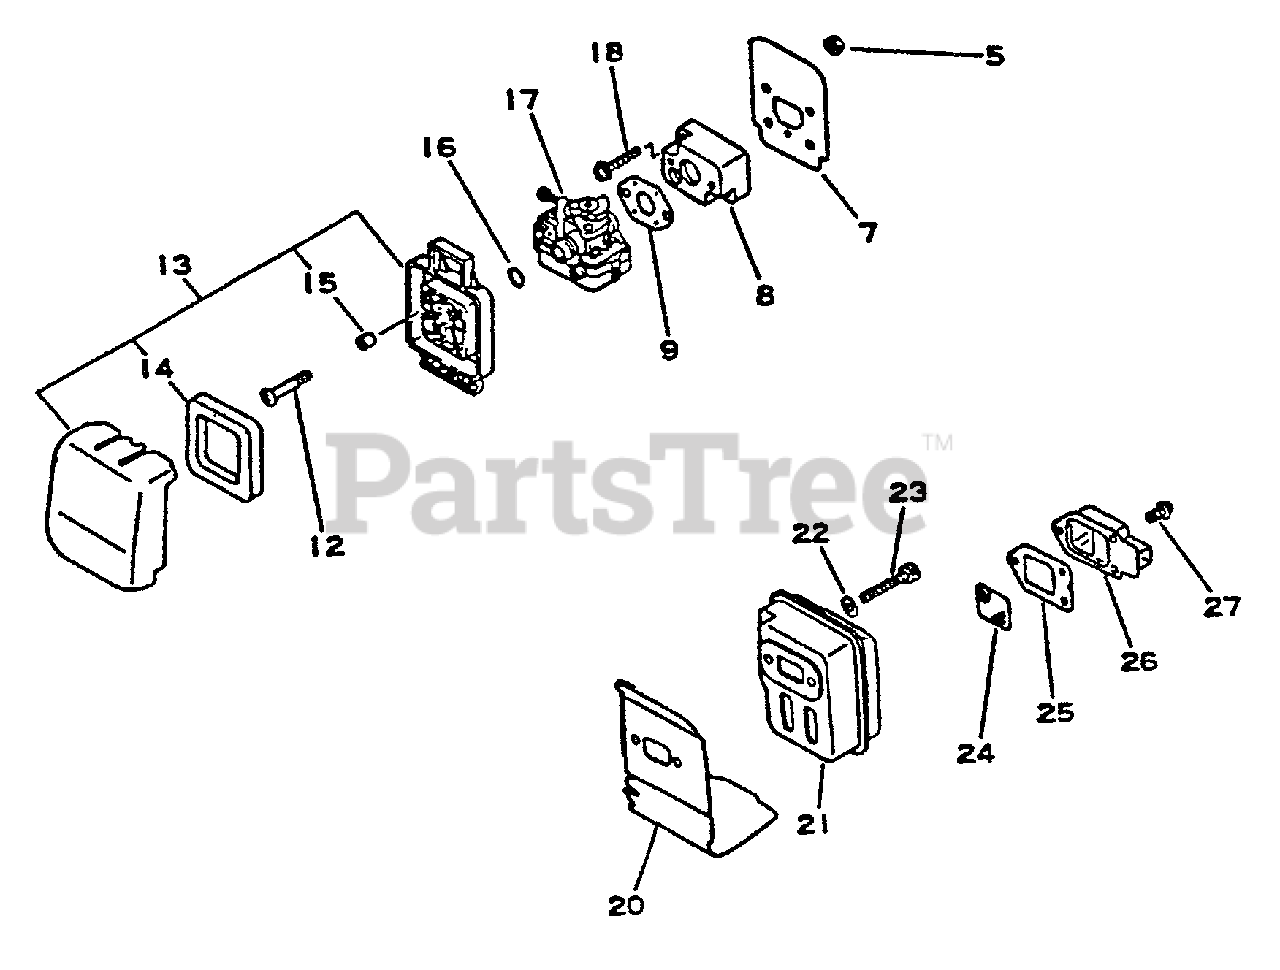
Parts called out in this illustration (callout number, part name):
5	NUT M5
7	HEAT SHIELD, INTAKE
8	INSULATOR, INTAKE
9	GASKET, INTAKE
12	SCREW 5×64
13	AIR FILTER ASSY
14	FILTER, AIR
15	SLEEVE
16	O-RING 15
17	CARBURETOR - WYL-1
18	SCREW 5×22
20	GASKET, EXHAUST
21	MUFFLER
22	WASHER, FLAT 5.5×10×0.8
23	BOLT 5×55
24	SCREEN, SPARK ARRESTER
25	GASKET, EXHAUST
26	GUIDE, EXHAUST - INNER
27	SCREW 4×10
